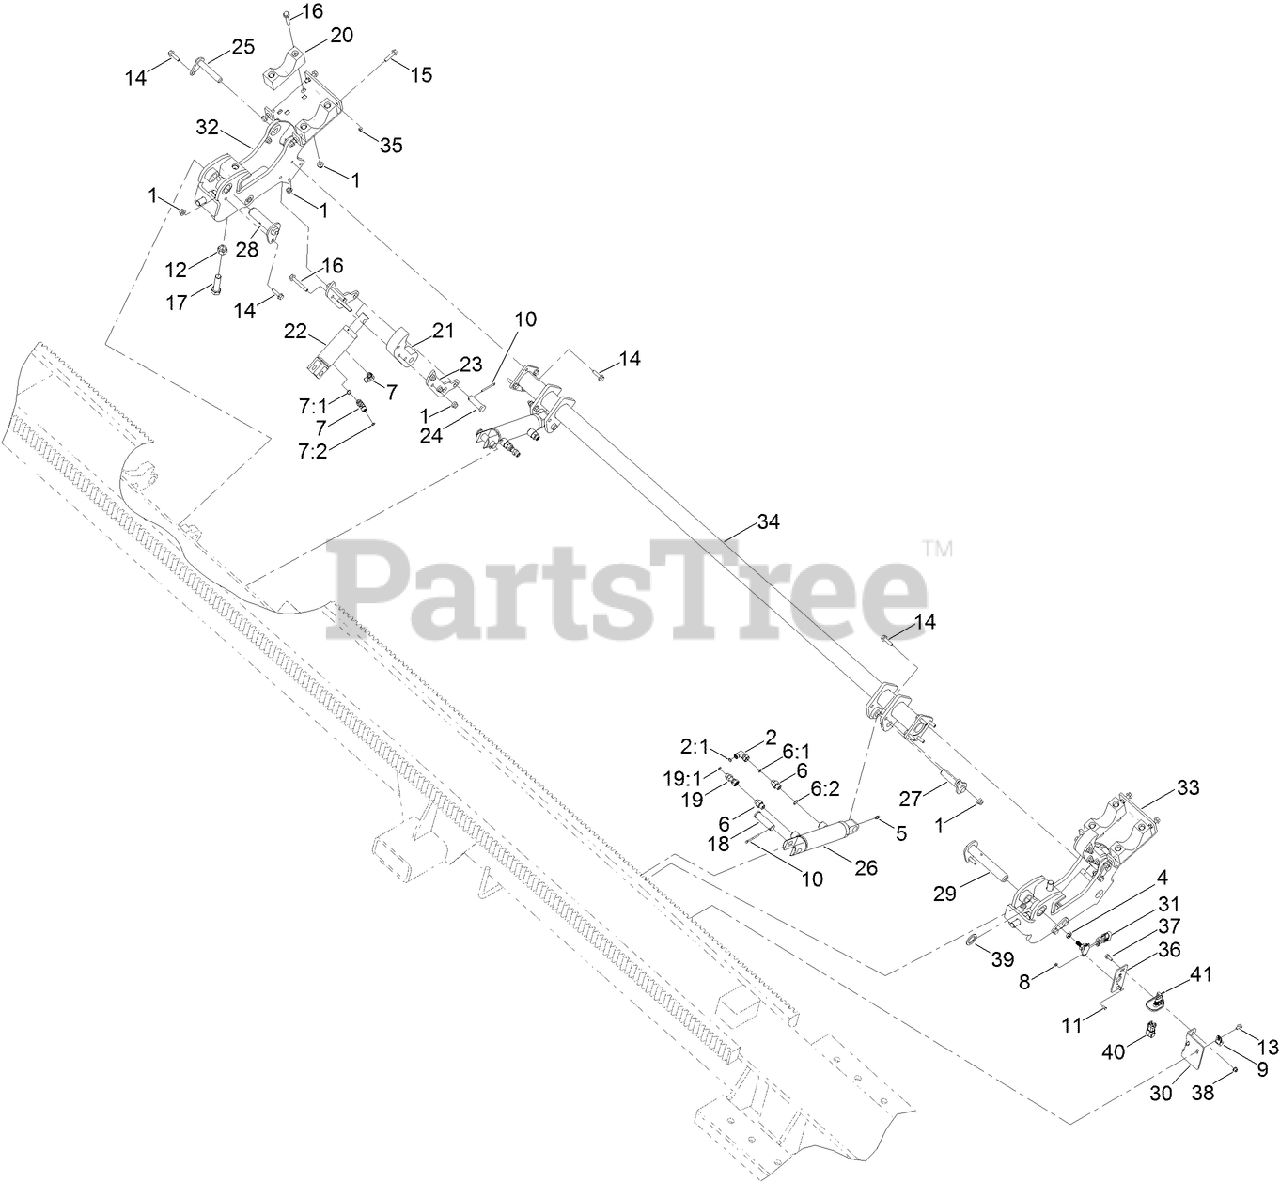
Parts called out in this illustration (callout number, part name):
1	NUT-LOCK, HHF
2	FITTING-ADAPTOR
2:1	O-RING
4	NUT-HEX
5	FITTING-GREASE
6	FITTING-STRAIGHT
6:1	O-RING
6:2	O-RING
7	FITTING-90 DEG
7:1	O-RING
7:2	O-RING
8	NUT-HHF
9	CLAMP-R
10	PIN-COTTER
11	SCREW-HH
12	NUT-HEX
13	SCREW-HHF
14	SCREW-HHF
15	SCREW-HHF
16	SCREW-HHF
17	SCREW-HH
18	PIN-CLEVIS
19	FITTING-STRAIGHT
19:1	O-RING
20	HOLDER-PIPE
21	INSERT-GRIPPER
22	HYD CYLINDER ASM
24	PIN-CLEVIS
25	PIN-PIVOT (W/ FLAG)
26	CYLINDER ASM
27	PIN-PIVOT
28	PIN-PIVOT, CAM
29	PIN-PIVOT
30	BRACKET-LOADER, ROD
31	SENSOR-ROTARY
32	LOADER-ROD, REAR
33	LOADER-ROD, FRONT
35	NUT-HEX
36	PLATE-SENSOR
37	SCREW-HHF
38	NUT-FLANGE, NI
39	WASHER-THRUST
40	HARNESS-ADAPTOR, SENSOR
41	TIE-CABLE
